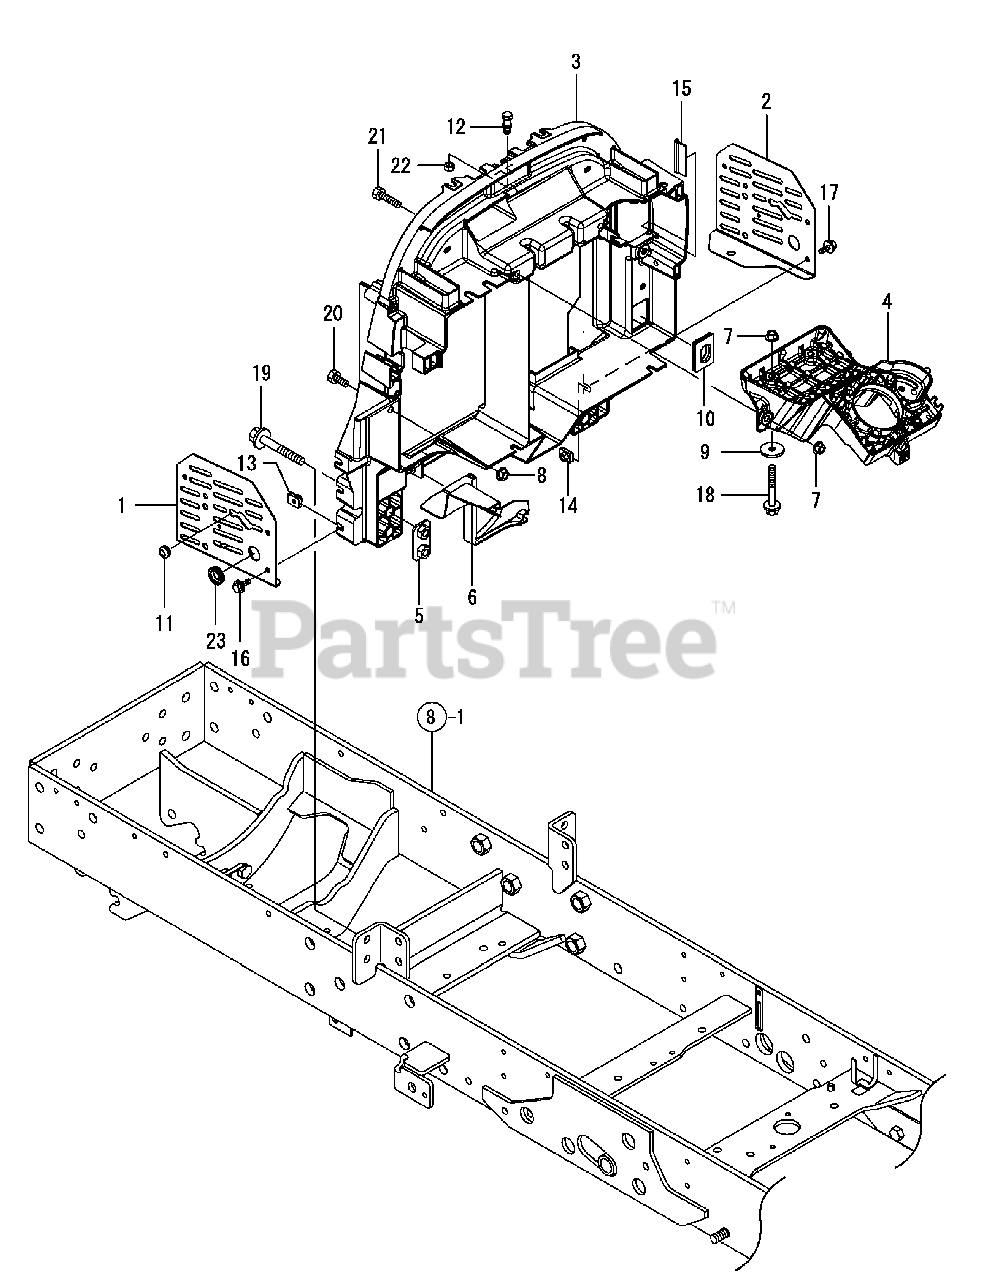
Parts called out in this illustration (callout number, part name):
1	COVER ASSY, LH, FAN BELT
2	COVER ASSY, RH, FAN BELT
3	BRACKET, COLUMN
4	BRACKET, STEERING
6	BOOT, DASHCOVER
7	NUT W/WASHER 8
8	NUT W/WASHER 8
9	WASHER 9X32X3.2
10	GROMMET, HARNESS
16	BOLT M 6X 16 PLATED
17	BOLT M 6X 16 PLATED
18	BOLT M 8X 65 PLATED
19	BOLT M10X 75 PLATED
20	BOLT M 8X 20 PLATED
21	BOLT M 8X 40 PLATED
23	GROMMET 16.0X2.0
